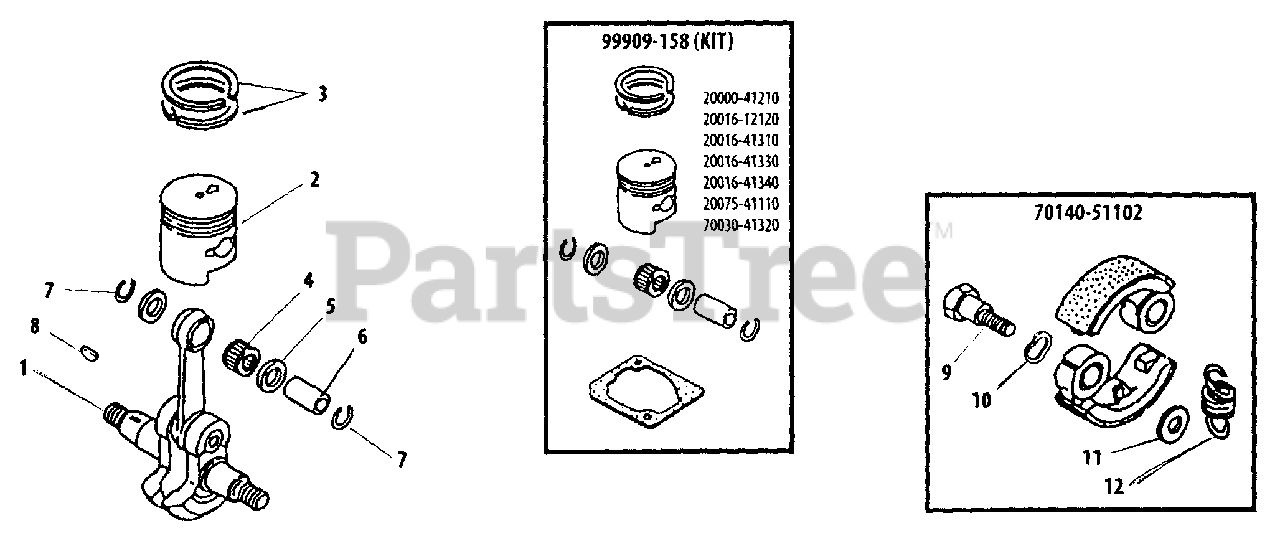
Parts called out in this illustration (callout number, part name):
1	CRANKSHAFT ASSY
2	PISTON
3	RING, PISTON
4	BEARING, NEEDLE
5	WASHER, THRUST
6	PIN, PISTON
7	RING, RETAINING
8	KEY - 3X10
9	BOLT, CLUTCH
10	WASHER - SPRING
11	WASHER - 6
12	SPRING, CLUTCH
70140-51102	CLUTCH ASSY
99909-158	PISTON ASSY
